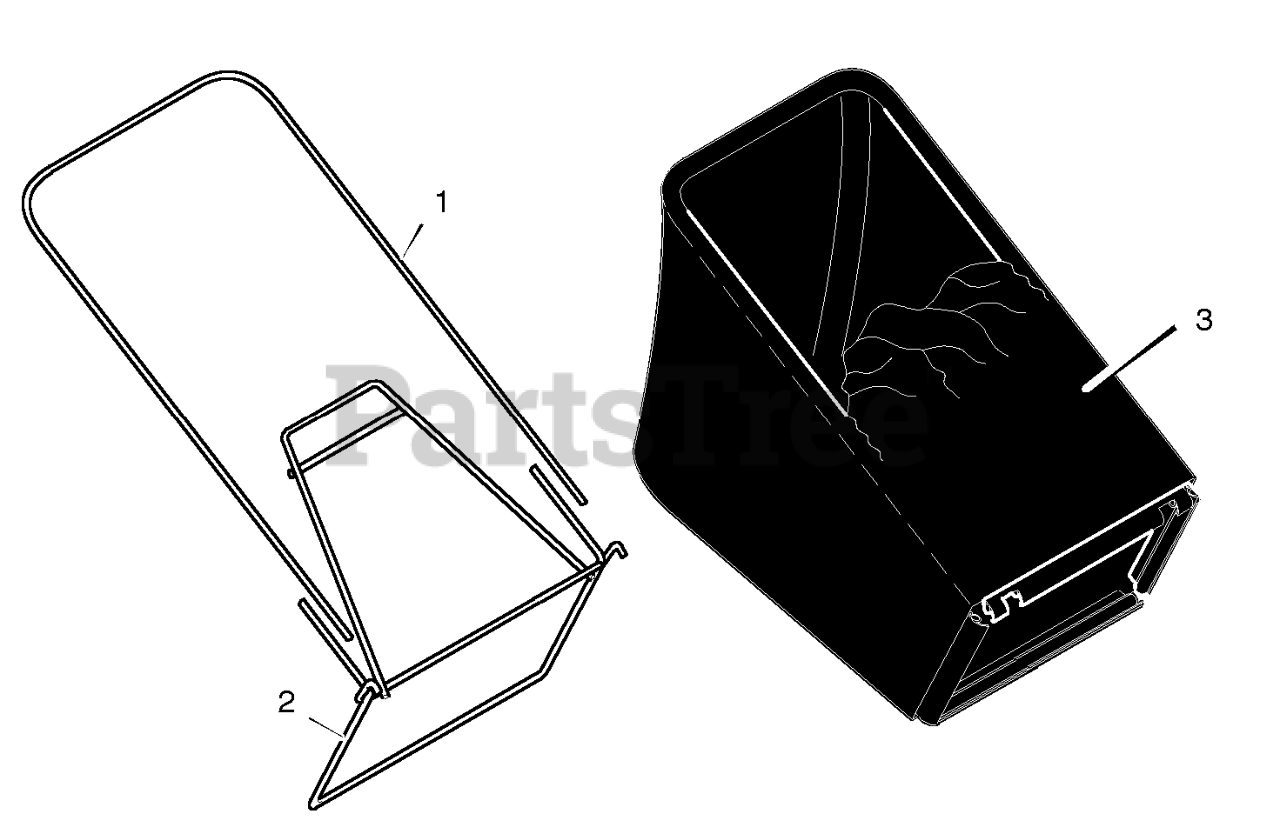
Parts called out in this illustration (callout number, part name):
1	Frame, Top
2	Frame Assembly
3	Bag, Cloth
